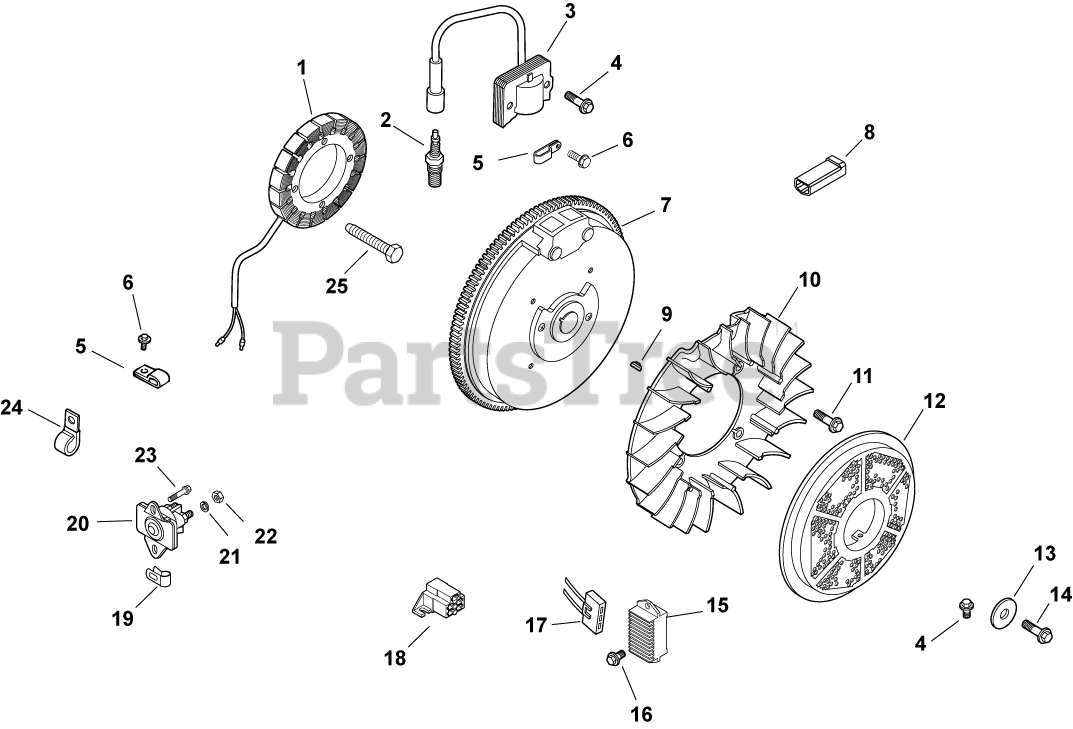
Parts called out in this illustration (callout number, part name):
1	KIT, 25 AMP STATOR ASSY.
2	PLUG, SPARK (STD)
3	MODULE, IGNITION
4	SCREW, FLG THD FRM M5X.8X20-(#25086399S)
6	SCREW, FLG THD FRM M5X.8X10
7	FLYWHEEL - USE 12 025 16-S
8	CONNECTOR (1 CONTACT)
9	KEY, 3/16" X 5/8"
10	FAN - DISCONTINUED
11	BOLT, SHOULDER
13	WASHER, FLAT 13/32"
14	SCREW, FLG M10X1.5X45 - (#25086361S)
15	REG/RECTIFIER (20/25 AMP)-USE 25 403 20-
16	SCREW, FLG M6X1.0X16
17	CONNECTOR, BODY (KM)-USE 25 155 41-S
18	CONNECTOR
20	SOLENOID - WATERPROOF (KM)-USE 25 435 08
21	WASHER, INT TOOTH LOCK 1/4"
22	NUT, JAM 1/4-20 GRADE 2
23	SCREW,FLG THD FRM M6X1.0X16-(#25086397S)
24	CLIP, CABLE
25	SCREW, THD FROM M5X0.8X30
